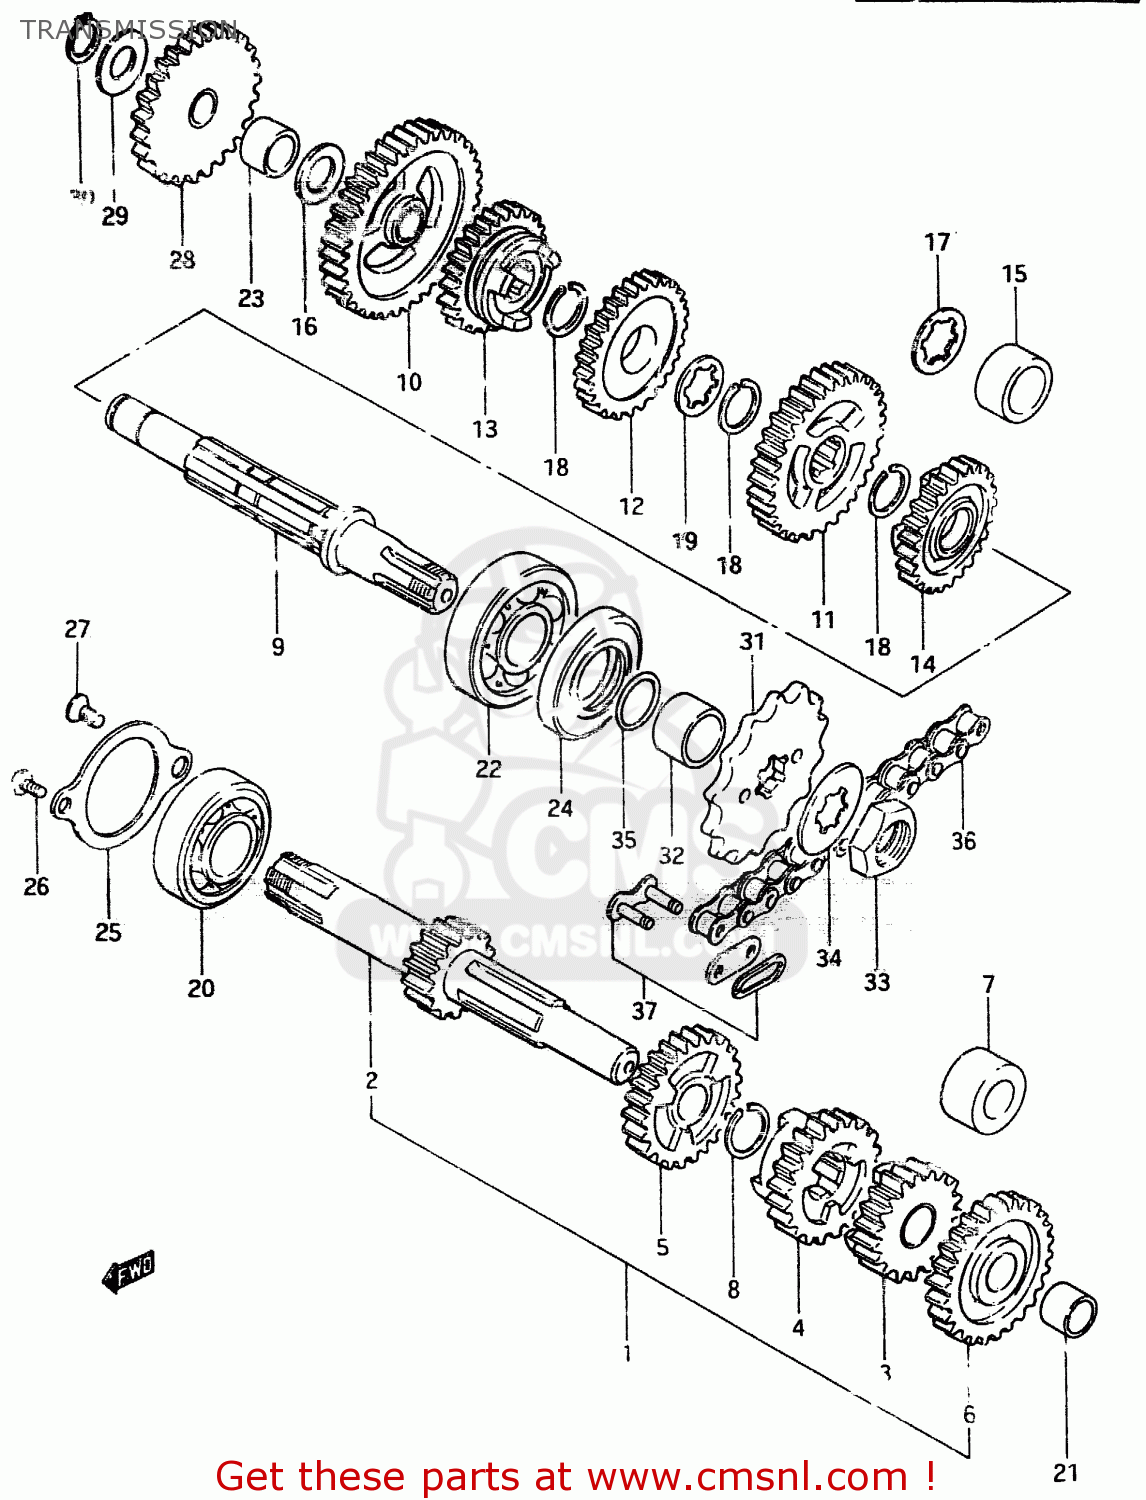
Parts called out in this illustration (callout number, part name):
1	SHAFT,COUNTER
2	SHAFT,COUNTER(NT:12)
3	GEAR,SECOND DRIVE
4	GEAR,THIRD DRIVE
5	GEAR,4TH DRIVE(NT:24)
6	GEAR,FIFTH DRIVE
7	SPACER
8	CIRCLIP
9	SHAFT,DRIVE
10	GEAR,FIRST DRIVEN
11	GEAR,2ND DRIVEN(NT:33)
12	GEAR,3RD DRIVEN(NT:29)
13	GEAR,FOURTH DRIVEN
14	GEAR,5TH DRIVEN(NT:24)
15	SPACER
16	WASHER(13X24X1)
17	WASHER,LOCK
18	CIRCLIP
19	WASHER,LOCK
20	BEARING
21	BUSH
22	BEARING
23	BUSH
24	SEAL,OIL(21X40X6)
25	RETAINER,CNTR SHAFT BEARING
26	SCREW
27	SCREW
28	GEAR,KICK STARTER IDLE
29	WASHER
30	CIRCLIP
31	SPROCKET,ENGINE
32	SPACER(17X21X13)
33	NUT
34	LOCK WASHER
35	O RING(D:1,ID:16.8)
36	CHAIN ASSEMBLY,DRIVE
37	JOINT ASSEMBLY,CHAIN
